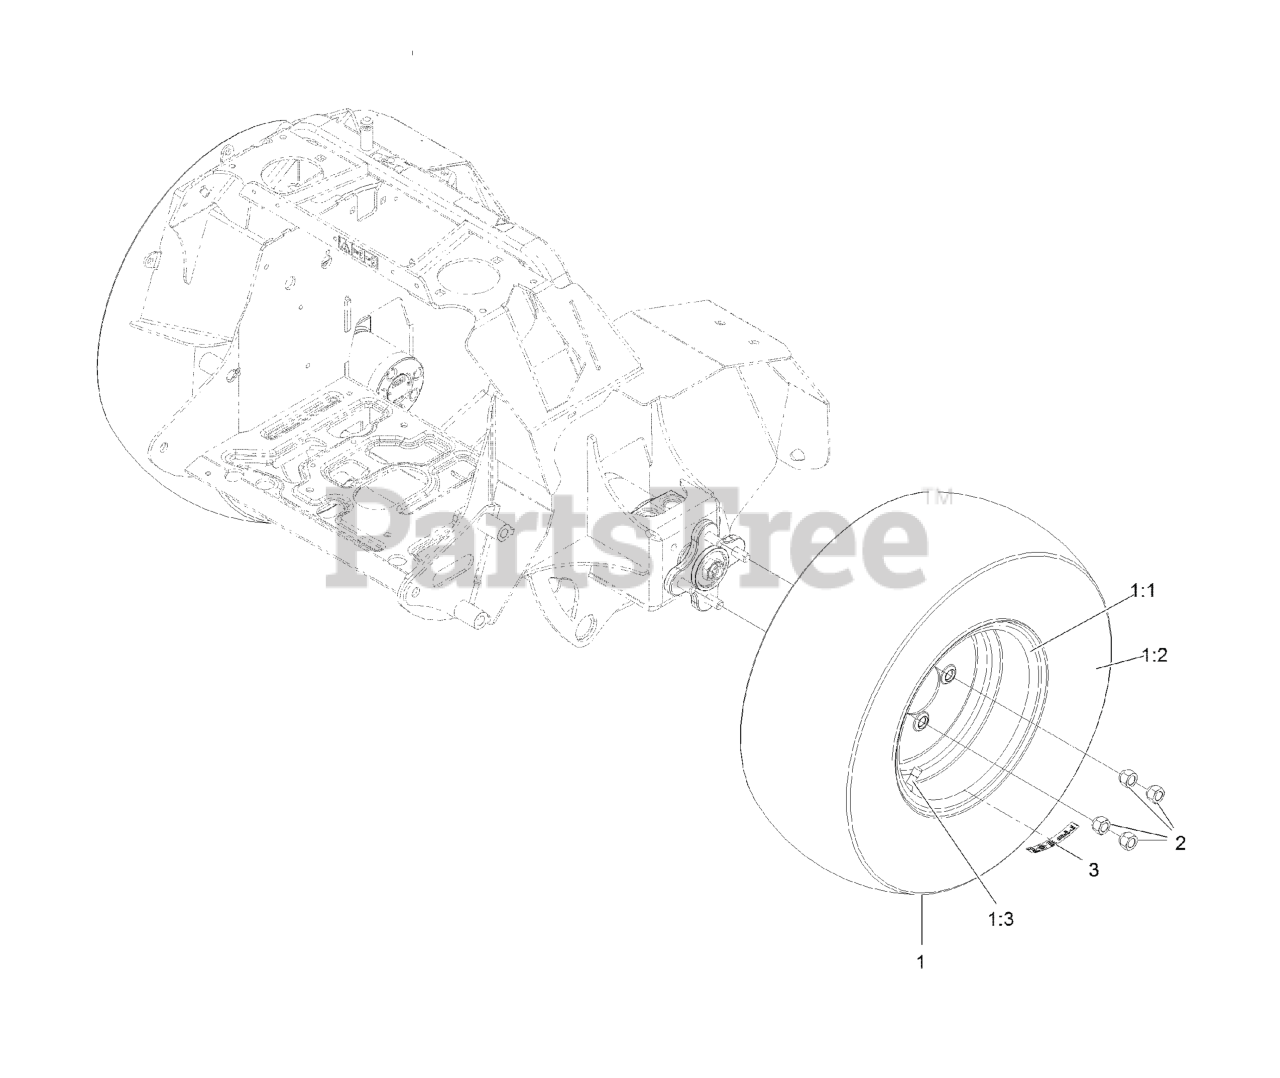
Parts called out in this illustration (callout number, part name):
1	ASM-WHL TIRE
1:1	WHEEL 10 X 6 WHT
1:2	TIRE-21X8.5-10
1:3	Stem-Valve
2	NUT-LUG
3	DECAL-TORQUE WHEEL LUG-HU
